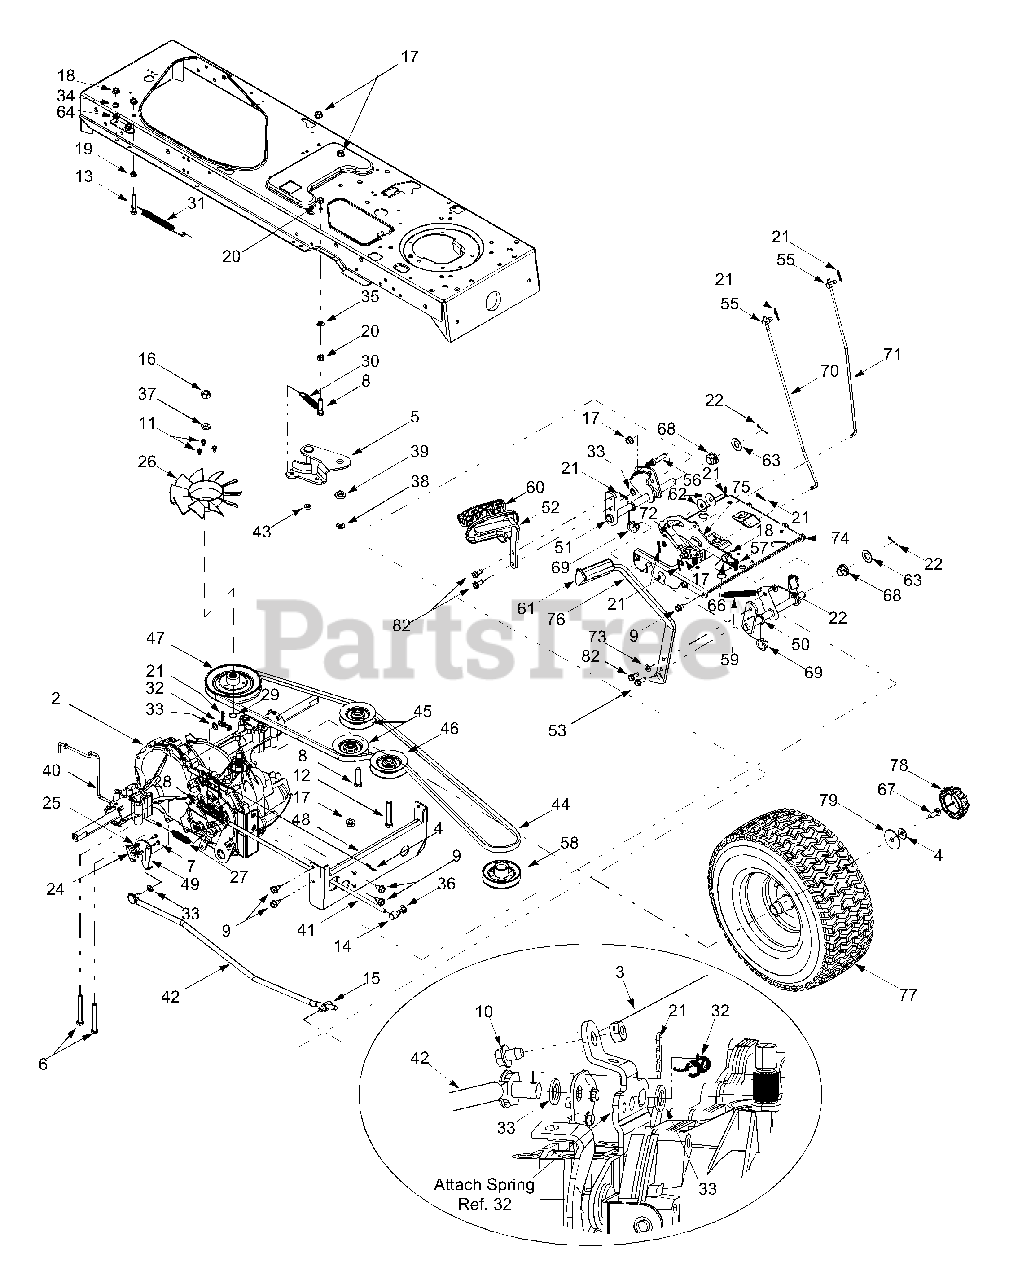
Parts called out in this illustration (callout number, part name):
2	Hydrostatic Transmission
3	Reverse Wire Harness Adapter & Ground
4	Bell Washer, .34 x .872
5	Double Idler Bracket Assembly
6	Hex Cap Screw, 5/16-18 x 2.75
7	Screw, #8-18 x .5
8	Hex Cap Screw, 3/8-16 x 1.5
9	AB Screw, 5/16-12 x .75
10	Self-tapping Screw, 1/4-20 x .375
11	Screw, #12-24 x .375
12	Hex Cap Screw, 3/8-16 x 2.25
13	Hex Cap Screw, 5/16-18 x 2.0
14	Ferrule, 5/16-18
15	Ferrule, 3/8-24
16	Hex Nut, 1/2-20
17	Flange Lock Nut, 3/8-16
18	Flange Lock Nut, 1/4-20
19	Hex Nut, 5/16-18
20	Hex Nut, 3/8-16
21	Internal Cotter Pin
22	Cotter Pin
23	Cable Tie
24	Short Spring Switch
25	Insulator Nut Plate
26	10-inch Fan
27	Extension Spring, .48 x 2.03
28	Extension Spring, .59 x 4.0
29	Wire Ring
30	Extension Spring, .5 x 3.97
31	Extension Spring, .5 x 7.0
32	Extension Spring, 3/8 x 1.44
33	Flat Washer, .385 x .62 x .063
34	Lock Washer
35	Lock Washer, 3/8
36	Flat Washer, .344 x .688 x .065
37	Lock Washer, 1/2
38	Flat Washer, .407 x .812 x .135
39	Shoulder Spacer, .38
40	Hydrostatic Bypass Rod
41	Hydrostatic Brake Rod
42	Hydrostatic Control Rod
43	Spacer, .376 x .625 x .22
44	Drive Belt
45	V-idler Pulley, 3.06
46	Flat Idler Pulley, 2.75
47	Input Pulley, 5.0
52	Hydro Pedal Assembly
53	Self-tapping Screw, 5/16-18 x .875
54	Self-tapping Screw, 5/16-18 x .75
55	Ferrule, 1/4-20
56	Pin, 3/8-16 x 2.43
57	Compression Spring, .405 OD x 1.17
58	Engine Pulley
59	Extension Spring, .50 OD x 6.37
60	Drive Pedal Pad
61	Brake Pedal Pad
62	Flat Washer, .411 x 1.25 x 1.0
63	Flat Washer, .64 x 1.24 x .06
64	Ext. Lock Washer
65	TT Screw 5/16-18 x 0.75
66	Shoulder Screw, .437 x 1.62
67	Hex Cap Screw, 5/16-24 x .75
68	Hex Flange Bearing
69	Split Hex Flange Bearing
70	Cruise Control Rod
71	Brake Lock Control Rod
72	Cruise Latch
73	Flat Washer, .344 x .750 x .120
75	Drive Lockout Bracket
78	Deluxe Hub Cap (Ref. 79 Required)
79	Flat Washer, .350 x 1.59 x .062
